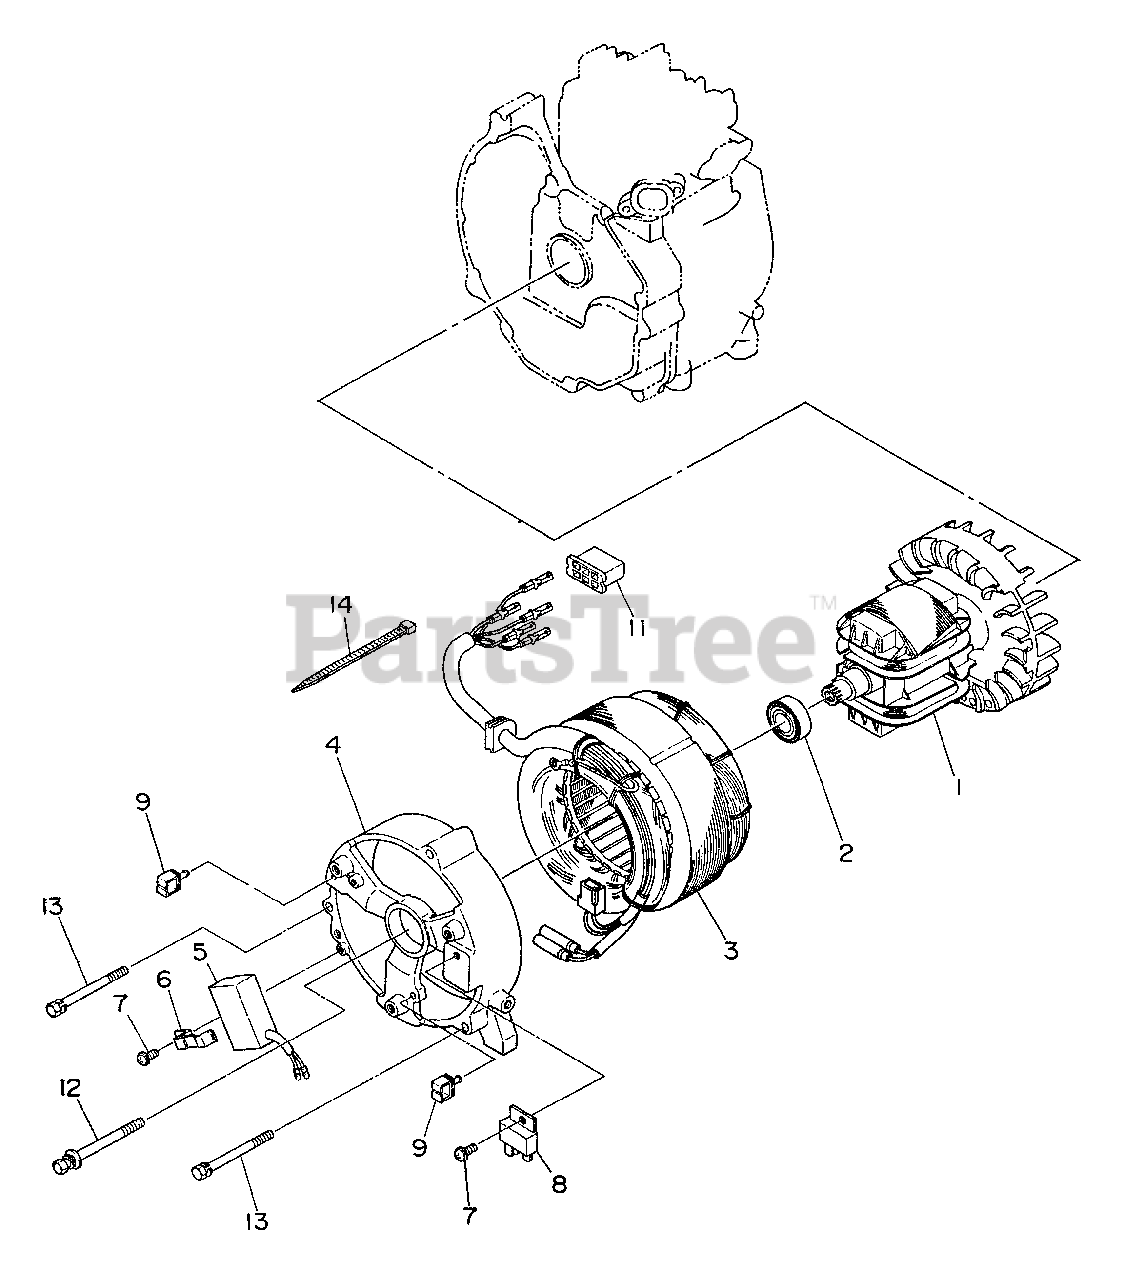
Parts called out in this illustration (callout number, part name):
1	ROTOR ASSY
2	BEARING, BALL
3	STATOR ASSY -- 60Hz-120V
5	CONDENSER
6	BAND
7	SCREW
8	RECTIFIER
9	CLAMP
11	CONNECTOR
12	BOLT
13	BOLT
14	TIE, CABLE
